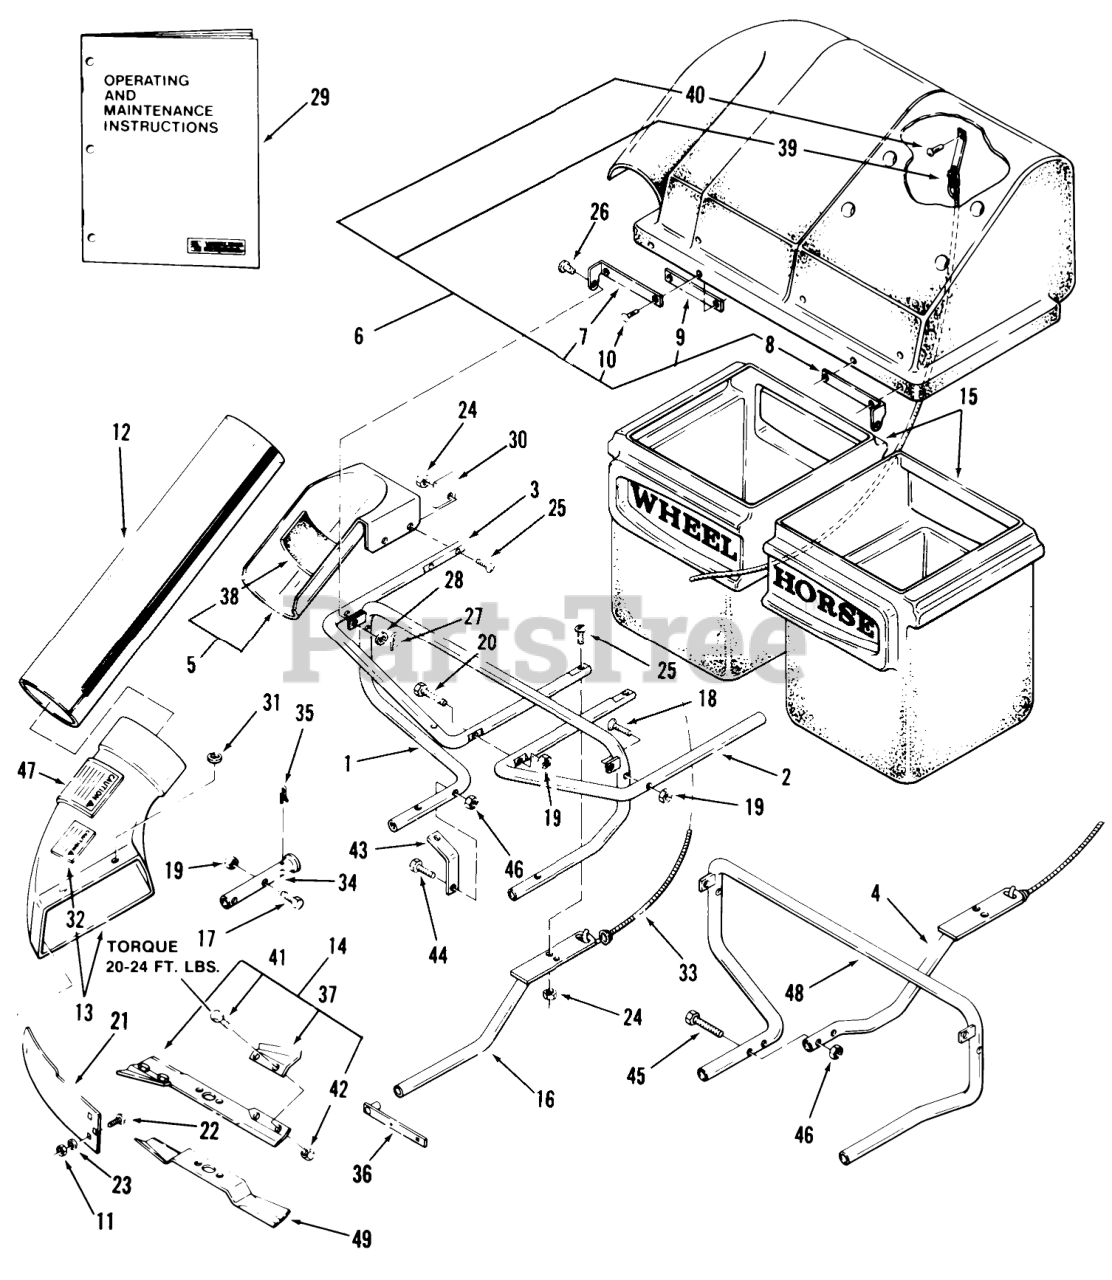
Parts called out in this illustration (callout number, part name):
1	ASSY-MAIN FRAME
2	SUPPORT-LEFT TUBE
3	Support Tube R.H.
4	Brace Tube
5	Collector Tube Suport
6	Collector Top Assy.
7	Hinge R.H.
8	Hinge L.H.
9	BACKING PLATE
10	Poprivet 5/32 x 1/2 Long
11	Nut
12	Tube
13	ASSY-ELBOW
13	Elbow
14	High Lift Blade
14	ASSY-HI LIFT BLADE
15	CAN-CLIPPINGS
16	Brace Tube
17	HHCS
18	Screw Flat Hd. Mach. 5/16 x 2 1/2
19	Nut
20	HHCS
21	BAFFLE-DEFLECTOR B
22	Bolt Carnage
23	Lockwasher
24	Nut
25	Screw Flat Hd. Mach. 1/4-20 x 1 1/2
26	PIN
27	Hairpin Cotter
28	Washer
29	Operating and Maintenance Instructions
30	PLATE-BACKUP
31	Collar
32	DECAL-CAUTION
33	Strap
34	Quick-Attach Tube
35	Pin-Cotter
36	ASSY-MOUNTING PIN
37	Lift Tab Kit
37	S/A 37 LIFT TAB KIT
39	Bracket
40	POPRIVET
41	BOLT 5/16-18X5/8
42	NUT-LOCK 5/16-18
43	BRACKET
44	Bolt
45	HHCS
46	Nut
47	Caution Decal
48	ASSY-MAIN FRAME
49	BLADE 16.50
